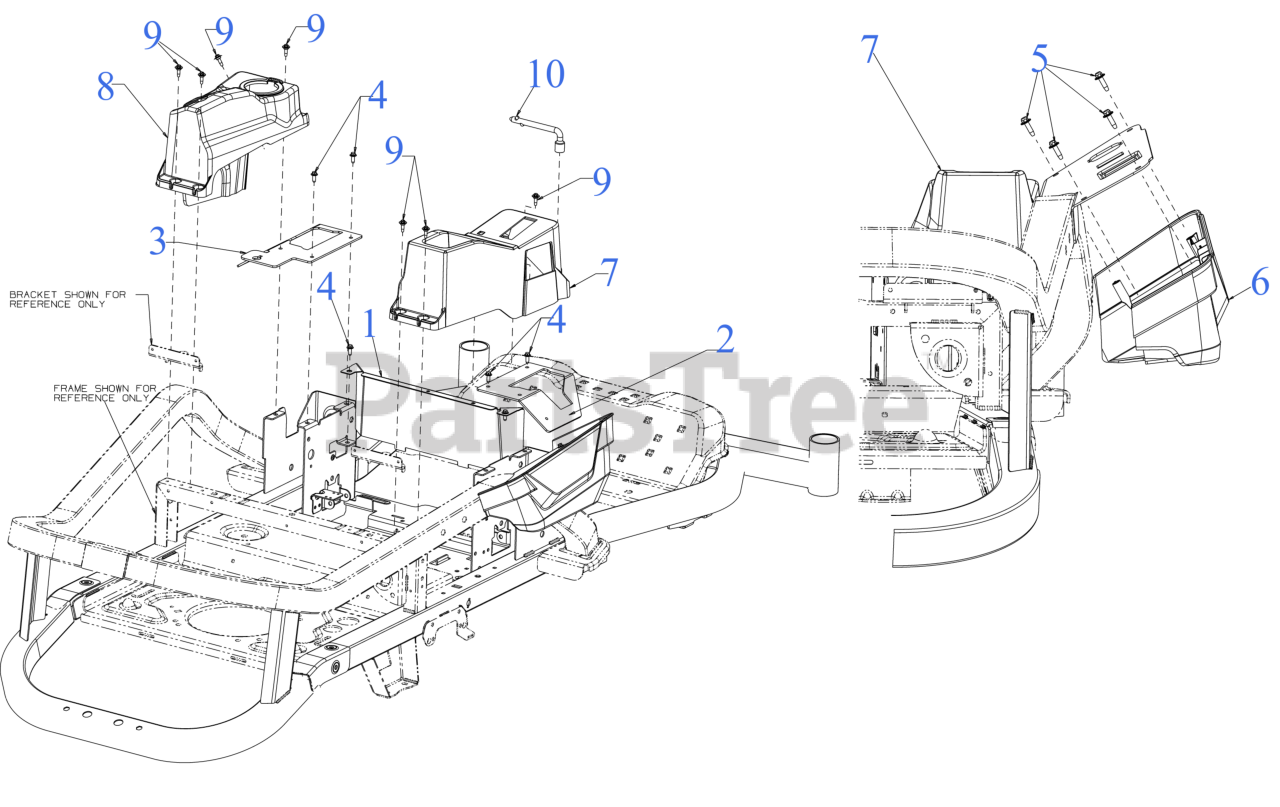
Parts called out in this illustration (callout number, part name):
1	SEAT BOX FRONT PLATE
2	CONTROL BRACKET (RH)
3	CONTROL BRACKET (LH)
4	SCREW M6-1 x .625
5	SCREW 1/4-10 x .750
6	CONTROL PANEL CONSOLE
7	CONSOLE (RH)
8	CONSOLE (LH)
9	SHOULDER SCREW M6-1 .368 X.115
10	MULTI TOOL 1/2" SOCKET
